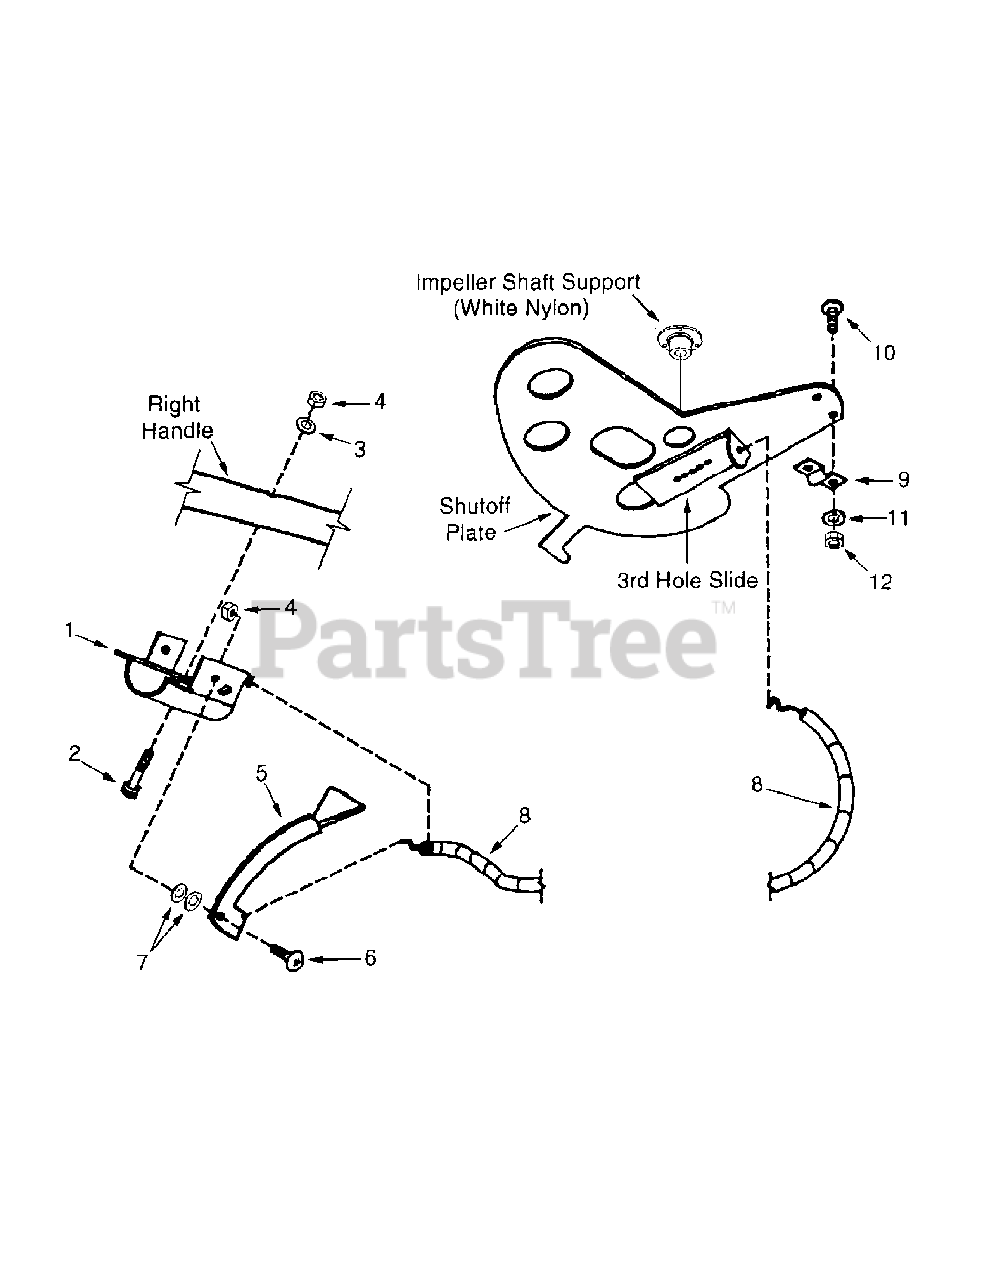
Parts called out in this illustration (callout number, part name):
1	Bracket, Dual Lever
2	Machine Screw
3	Flat Washer 1/4
4	Hex Nut, 1/4-20 Nylock
5	Lever, Dual Remote
6	Machine Screw
7	Flat Washer, 1/4 Nylon
8	Control Cable
9	Cable Clamp
10	Machine Screw
11	Lock Washer #8
12	Hex Nut, #8-32
